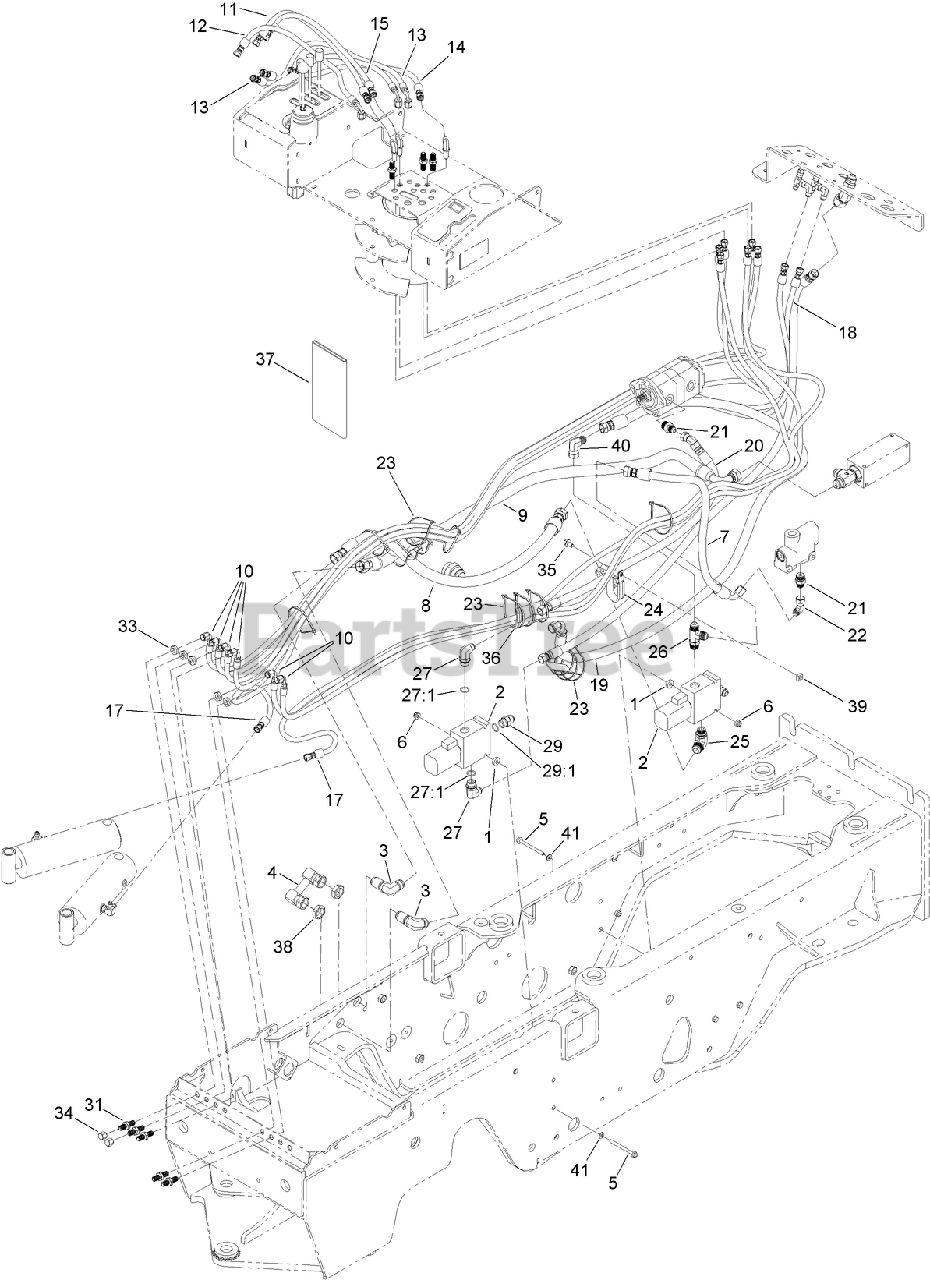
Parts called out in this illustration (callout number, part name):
1	SPACER-PIN, MOUNTING
2	DIRECTIONAL VALVE ASM
3	FITTING-ELBOW, 90
4	FITTING-SPECIAL
5	SCREW-FLANGE
6	NUT-LOCK, HHF
7	HOSE ASM
8	HOSE ASM
9	HOSE ASM
10	HOSE ASM
11	HOSE ASM
12	HYD HOSE ASM
13	HOSE ASM
14	HOSE ASM
15	HYD HOSE ASM
17	HOSE ASM
18	HOSE ASM
19	HOSE ASM
20	HOSE ASM
21	FITTING-STRAIGHT
22	FITTING-SWIVEL, 45
23	TIE-CABLE
24	CLAMP-R, DOUBLE
25	FITTING-ELBOW, 90 DEG
26	FITTING-TEE
27	FITTING-90 DEG
27:1	O-RING
29	FITTING-STRAIGHT
29:1	O-RING
31	UNION-BULKHEAD
33	NUT-LOCK, BULKHEAD
35	SCREW-HHF
36	PROTECTOR-HOSE
37	SLEEVE-PROTECTIVE
38	NUT-LOCK, BULKHEAD
39	NUT-SQUARE
40	ADAPTOR
41	WASHER-PLAIN
